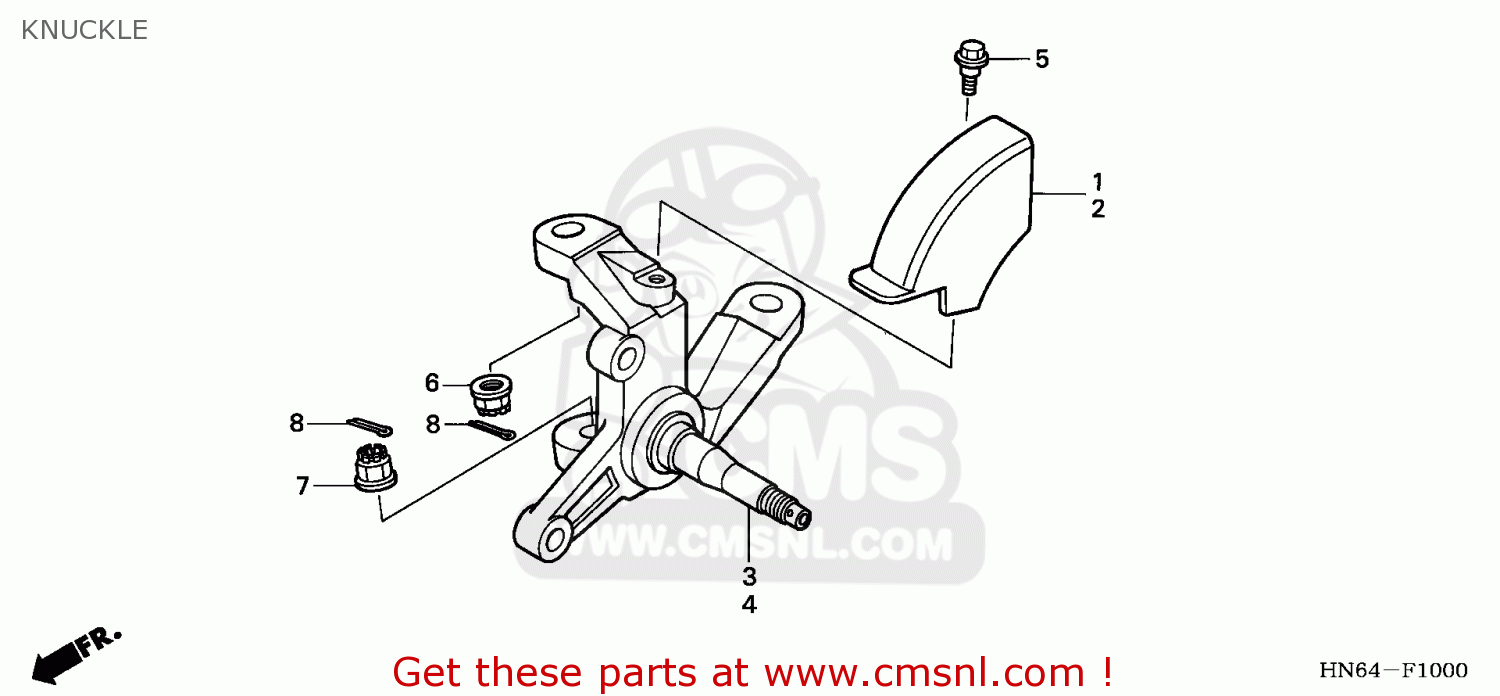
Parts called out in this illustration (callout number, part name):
1	COVER,R FR CALIPE
2	COVER,L FR DISK
3	KNUCKLE COMP,R
4	KNUCKLE COMP,L
5	BOLT FLANGE 6MM
6	NUT,CASTLE,12MM
7	NUT CASTLE 12MM
8	PIN COTTER 3.0MM
